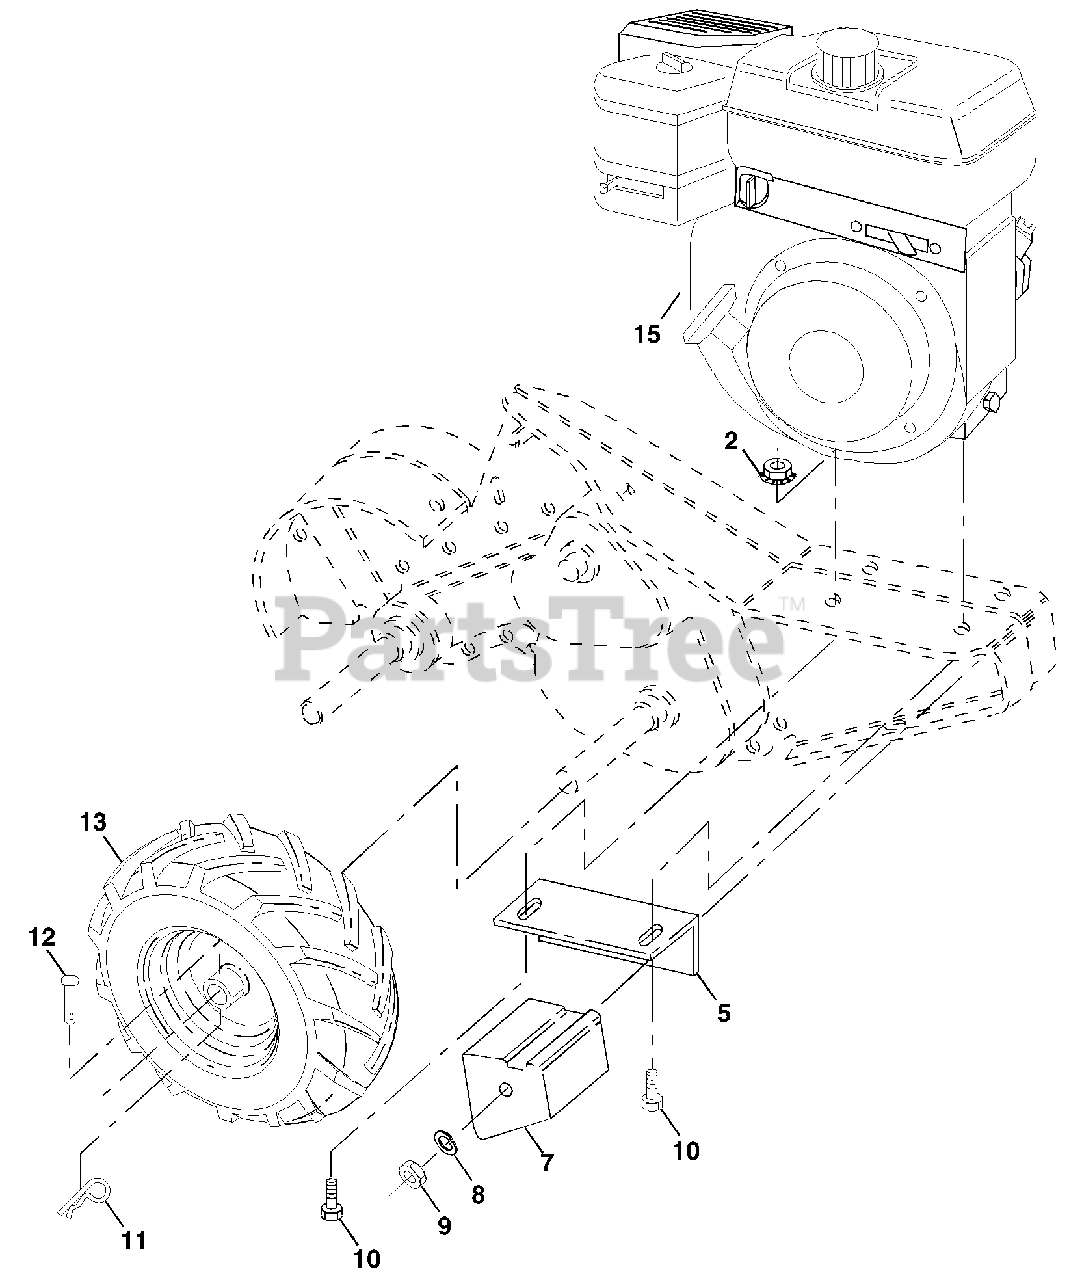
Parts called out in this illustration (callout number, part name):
2	Nut, Lock Hex Flange
5	Bracket, Reinforcement
7	Counter Weight, R.H.
8	Washer, Lock 3/8
9	Nut, Hex 3/8-16
10	Bolt, Hex 5/16-18 x 1-1/2
11	Clip, Hairpin
12	Rivet, Drilled
13	Tire
13	Tire Valve
